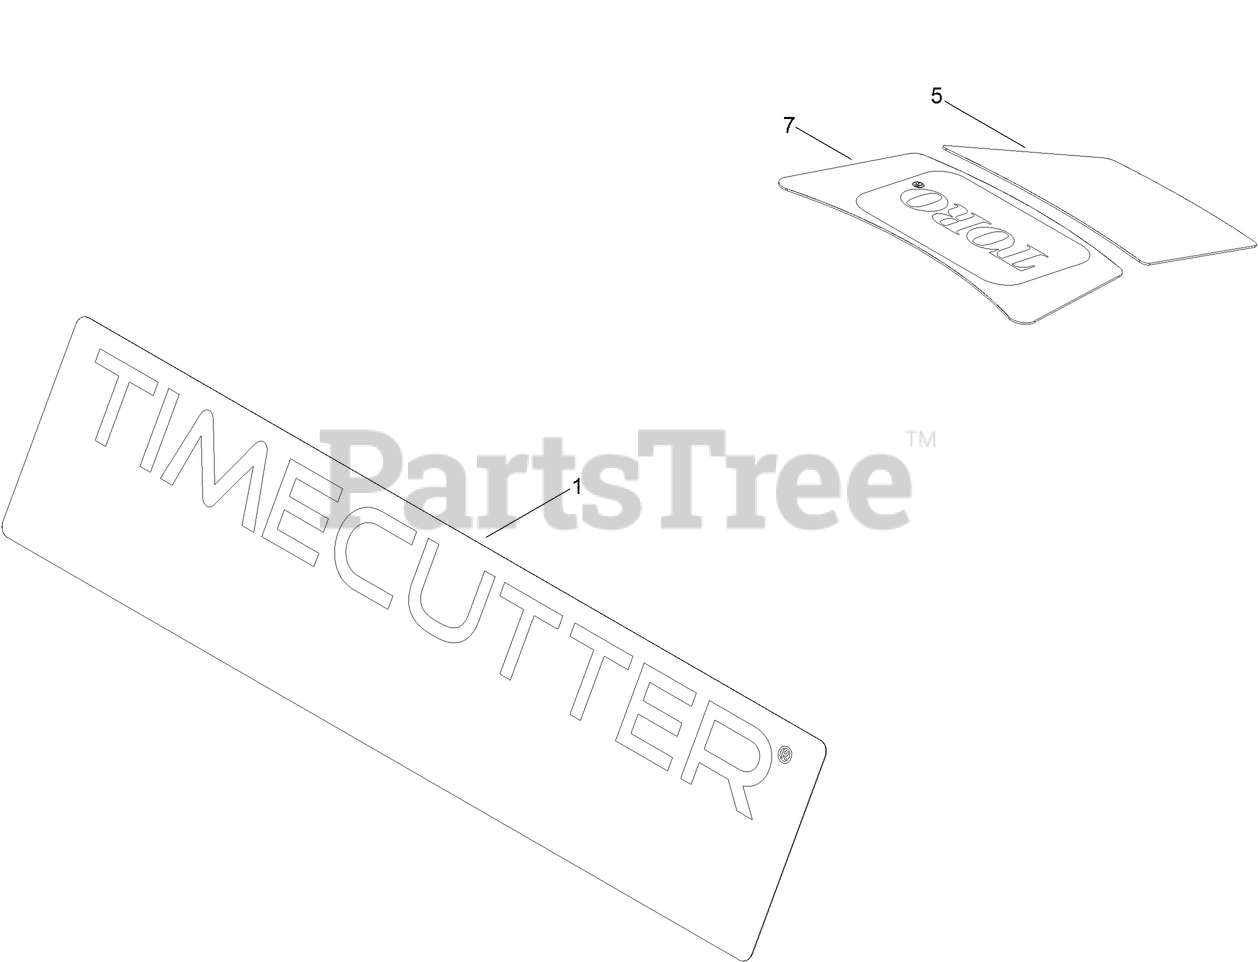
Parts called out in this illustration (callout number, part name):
1	DECAL-TIMECUTTER
5	DECAL-DISPLACEMENT, ENGINE
7	DECAL-ENGINE
